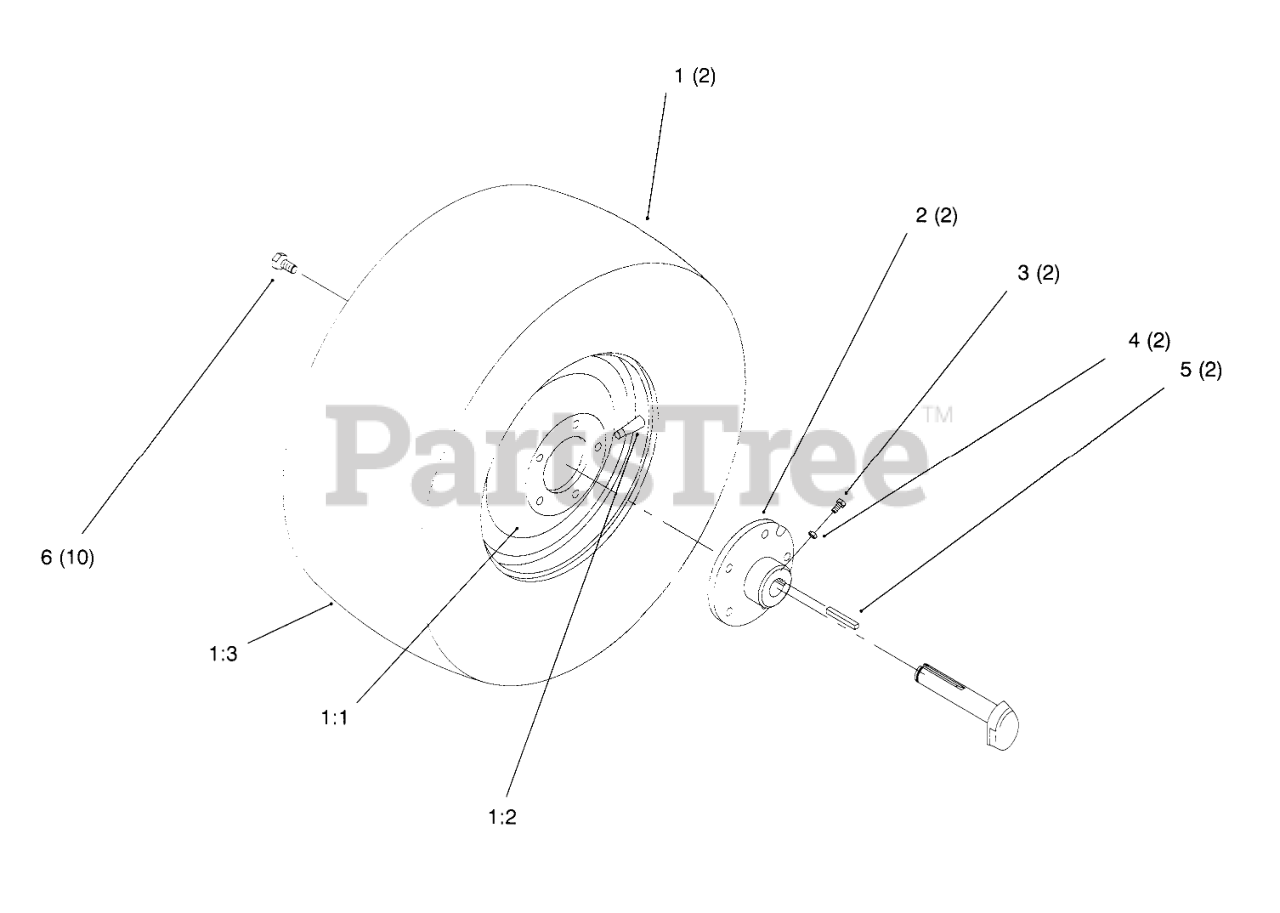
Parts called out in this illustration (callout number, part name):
1	Wheel & Tire ASM Rear
1:1	WHEEL
1:2	VALVE
1:3	TIRE 23 X 10.50-12
2	HUB-WHEEL
3	SCREW-SET, SQH
4	NUT-JAM
5	KEY-SQUARE
6	BOLT-LUG
